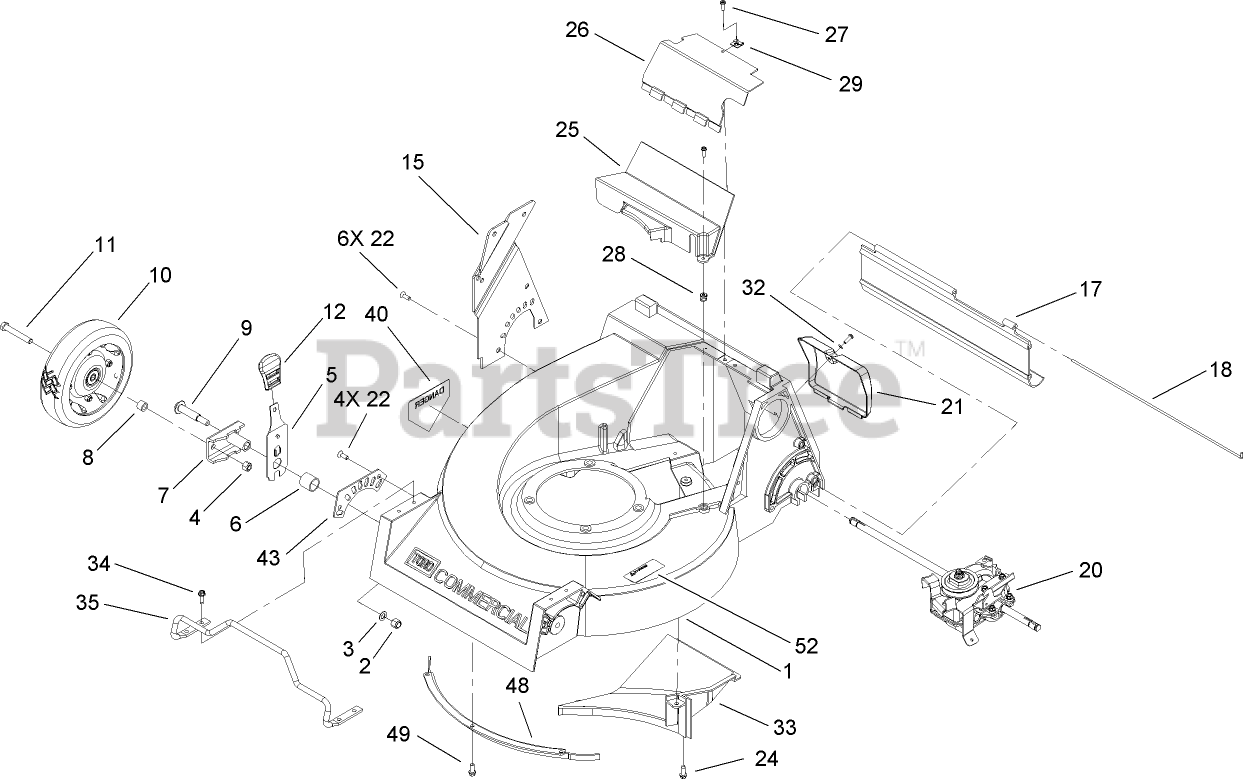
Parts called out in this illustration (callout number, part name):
2	NUT-LOCK
3	WASHER
4	NUT-LOCK, CONE
6	SPACER-BEARING
7	ARM-PIVOT, FRONT
8	SPACER-WHEEL
11	SCREW-HH
12	KNOB-HOC
17	SHEILD-TRAILING
18	ROD-SHIELD
20	GEAR CASE ASM
21	DOOR-ACCESS, REAR
22	SCREW-HH
24	SCREW-HWHTF
25	COVER-BELT, LOWER
26	COVER-BELT, UPPER
28	NUT-CLIP
29	NUT-TYPE J
32	WASHER-FLAT
34	SCREW-HWHTF
35	GUARD-ENGINE
40	DECAL-DANGER
49	SCREW-HWH
52	DECAL-DANGER
